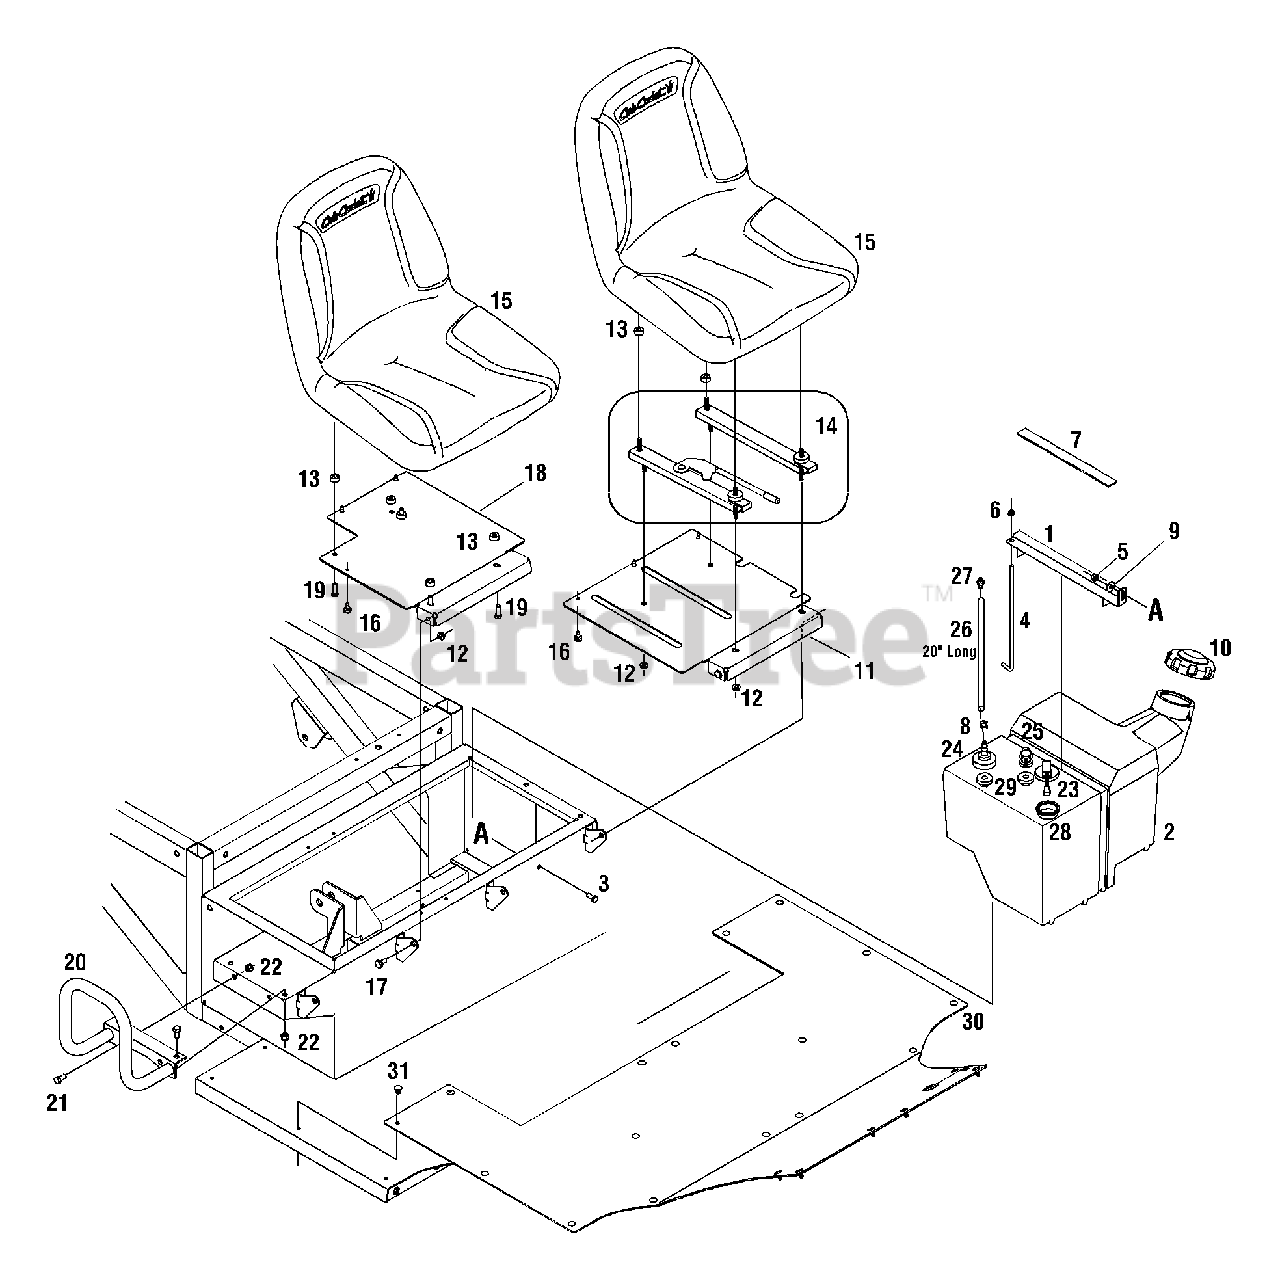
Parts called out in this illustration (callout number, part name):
1	Bracket Assembly, Fuel Tank
2	Tank Assembly, Fuel
3	Hex Screw, 5/16-18 x .75
4	Hold-down Rod, Fuel Tank
5	Sems Nut, 5/16-18
6	Nut, Flange Lock, 1/4-20
7	Gasket, Fuel Tank (11")
8	Clamp, Hose
9	Washer, .349 x .879 x .063
10	Cap, Fuel
11	Plate, Seat, LH
12	Nut, Flange Lock, 5/16-18, Gr5
13	Spacer, Seat
14	Track Assembly, Seat
15	Seat
16	Bumper
17	Shoulder Screw,.435 x.178-5/16 x.56
18	Plate, Seat, RH
19	Hex Screw, 5/16-18 x 1.0
22	Nut, Hex Lock Nylon, 3/8-16
23	Low Fuel Sensor
24	Fuel Return Fitting
25	Fuel Tank Shut Off Valve
26	Fuel Line Hose
29	Fuel Tank Grommet
31	Retainer Clip
